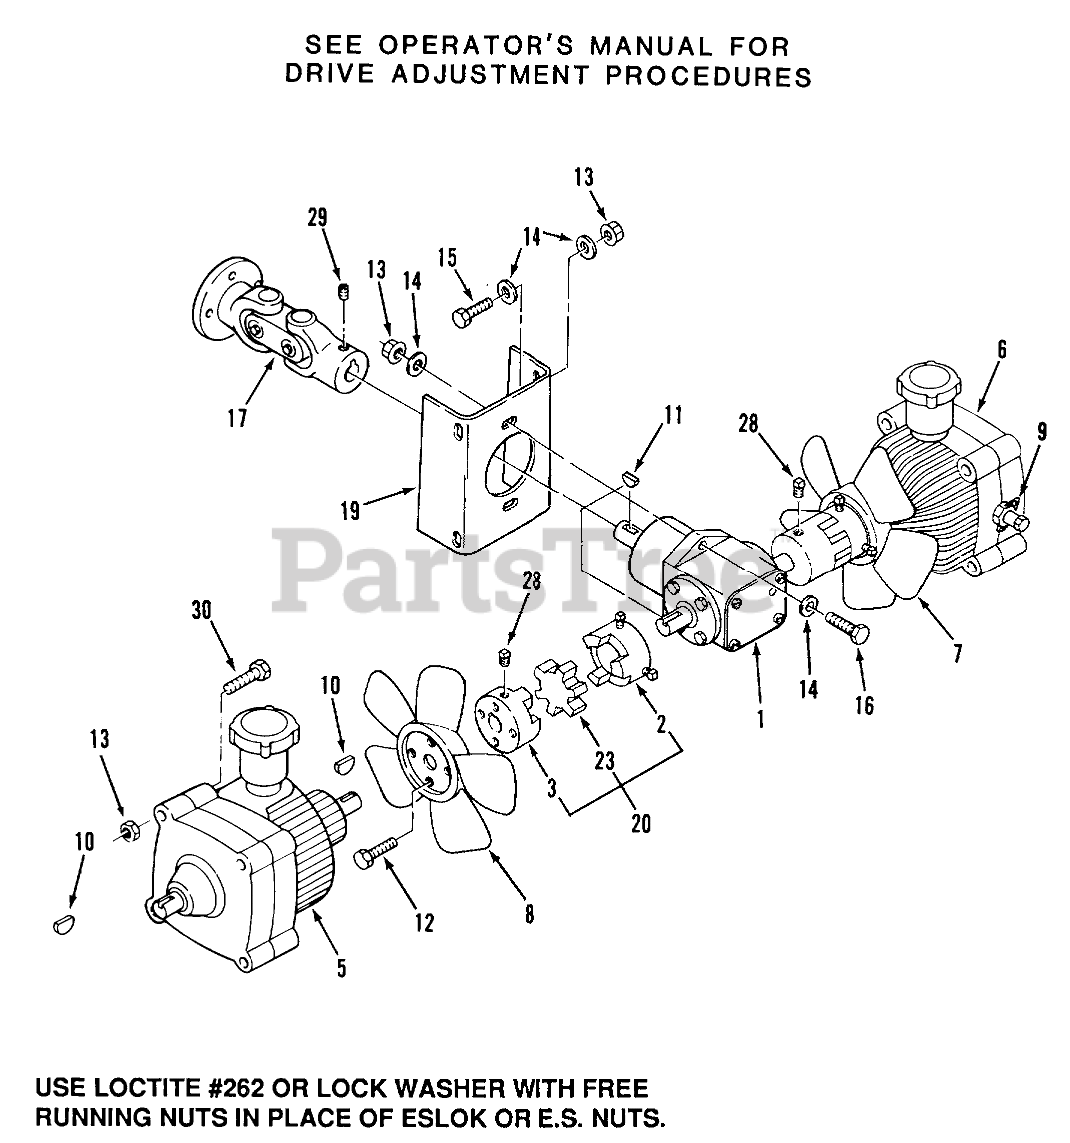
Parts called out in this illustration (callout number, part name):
1	GEAR BOX-T
2	COUPLING-KEYED
3	COUPLING-KEYED
5	TRANS-HYDRO CCW.
6	TRANS-HYDRO CW
7	Fan-LH, Clockwise
8	BLADE-FAN R.H.
9	CLIP-DUMP VALVE
10	KEY-HIPRO
11	KEY-HI-PRO
12	Screw
13	NUT
14	Washer
15	BOLT
16	Bolt
17	U-JOINT ASSY W/FLANGE
19	BRKT-GEAR BOX MOU B
20	Coupler Complete (includes 2,3 & 23)
23	SPIDER-COUPLING
28	Screw-Sq. Hd. Set
29	Setscrew 3/8-16 x 1/2
30	Screw-Hex. Hd.
43	NUT
44	Seat Switch
